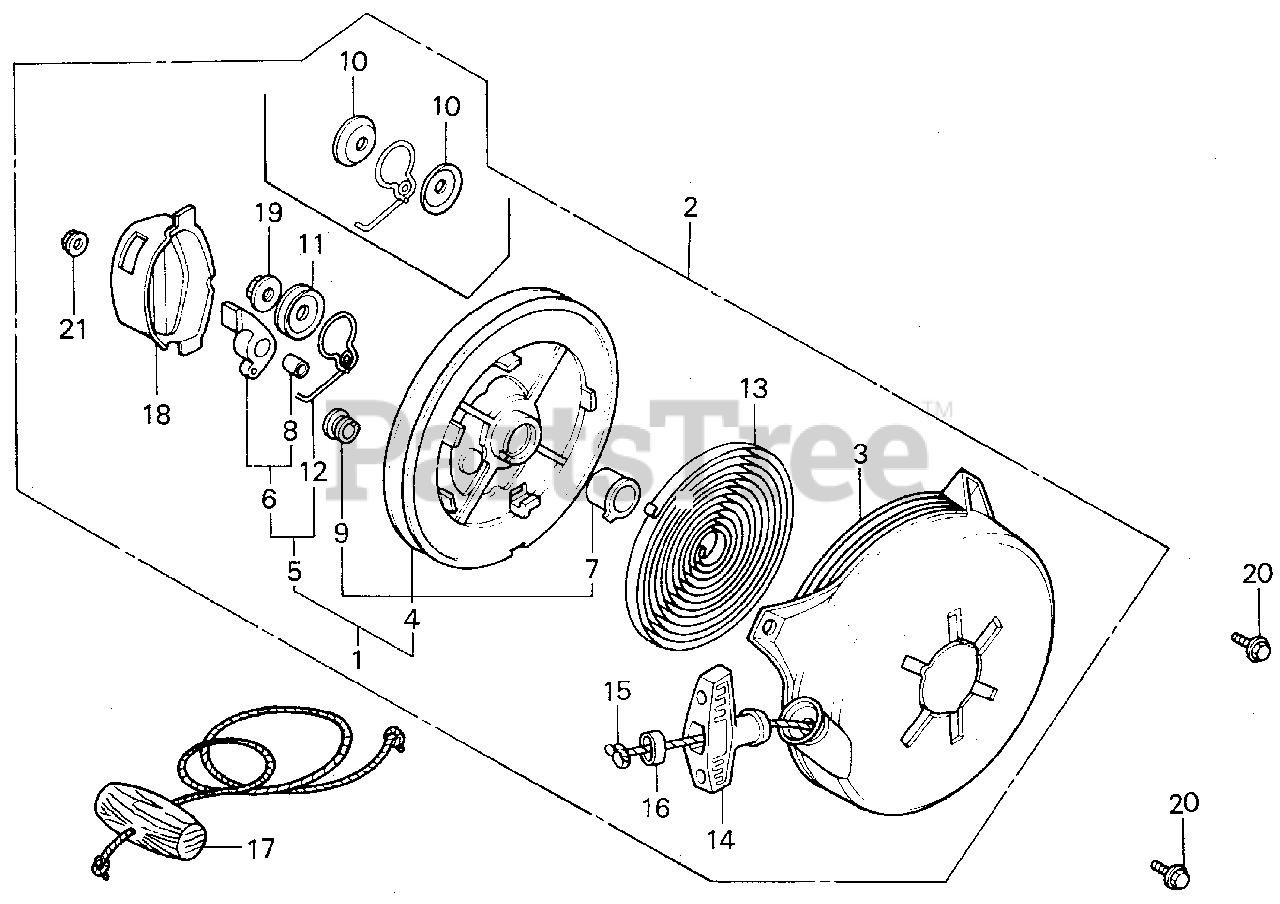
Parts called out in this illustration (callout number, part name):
1	REEL, STARTER
2	STARTER ASSY., RECOIL *R8* (BRIGHT RED)
3	CASE, STARTER *R8* (BRIGHT RED)
4	REEL, STARTER
5	RATCHET KIT
6	RATCHET KIT
6	RATCHET
7	BOSS, REEL
8	BUSH, RATCHET
9	BUSH, REEL STARTER
10	PLATE, FRICTION
11	PLATE, FRICTION
12	RATCHET KIT
12	SPRING, FRICTION
13	SPRING, RETURN
14	GRIP, STARTER
15	ROPE, RECOIL STARTER (#5X55")
16	SUPPORT, GRIP
17	ROPE, STARTER (#5X55") Use from Engine SN 1453515.
18	COVER, REEL STARTER
19	NUT, SELF-LOCK (8MM)
20	BOLT-WASHER (6X10)
21	NUT, FLANGE (5MM)
